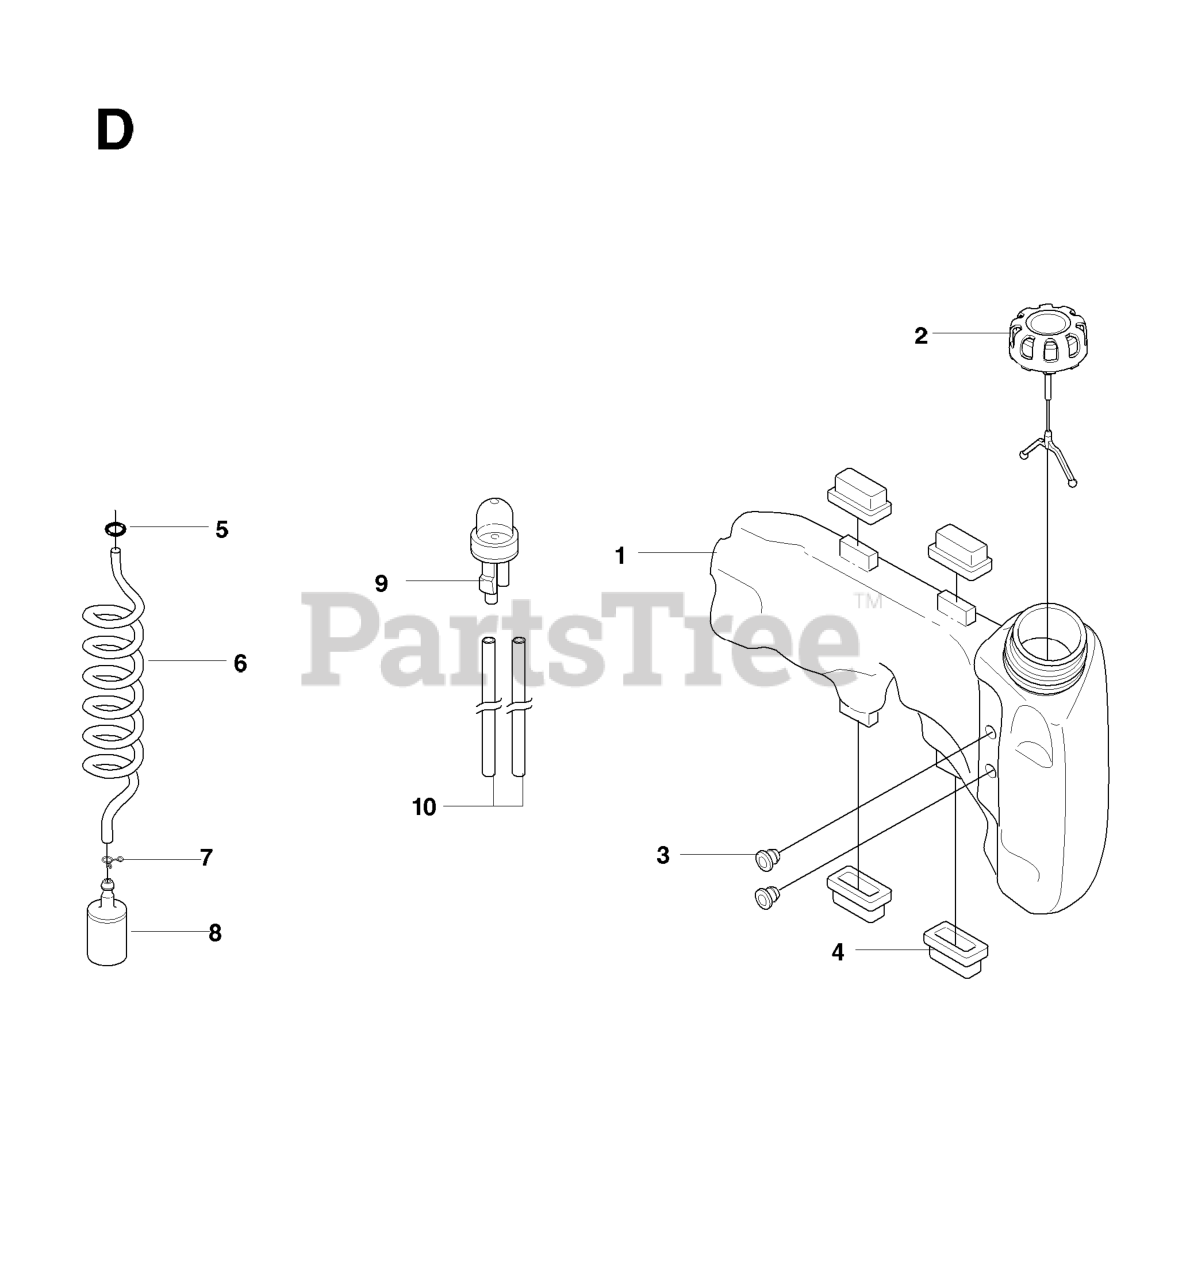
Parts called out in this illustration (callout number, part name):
2	TANK CAP
3	FUEL TANK BUSHING
6	FUEL HOSE
8	RP FUEL FILTER
9	AIR PURGE BUBBLE
10	HOSE
